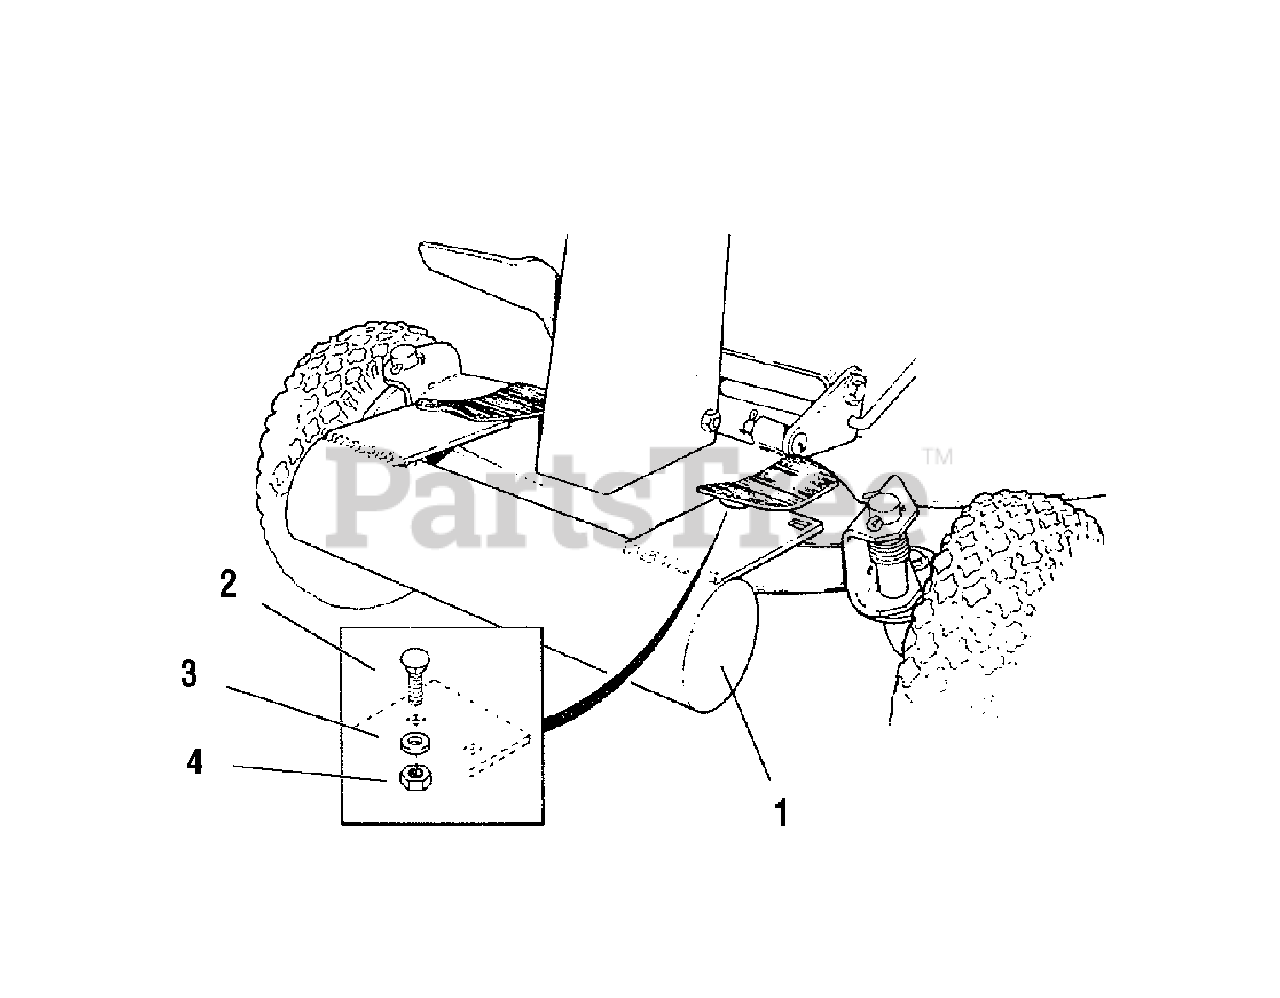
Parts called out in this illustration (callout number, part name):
1	COUNTERWEIGHT ASSEMBLY
2	BOLT, Carriage, 3/8-16 X 1
3	LOCKWASHER, 3/8
4	NUT, Hexagon, Full 3/8-16
